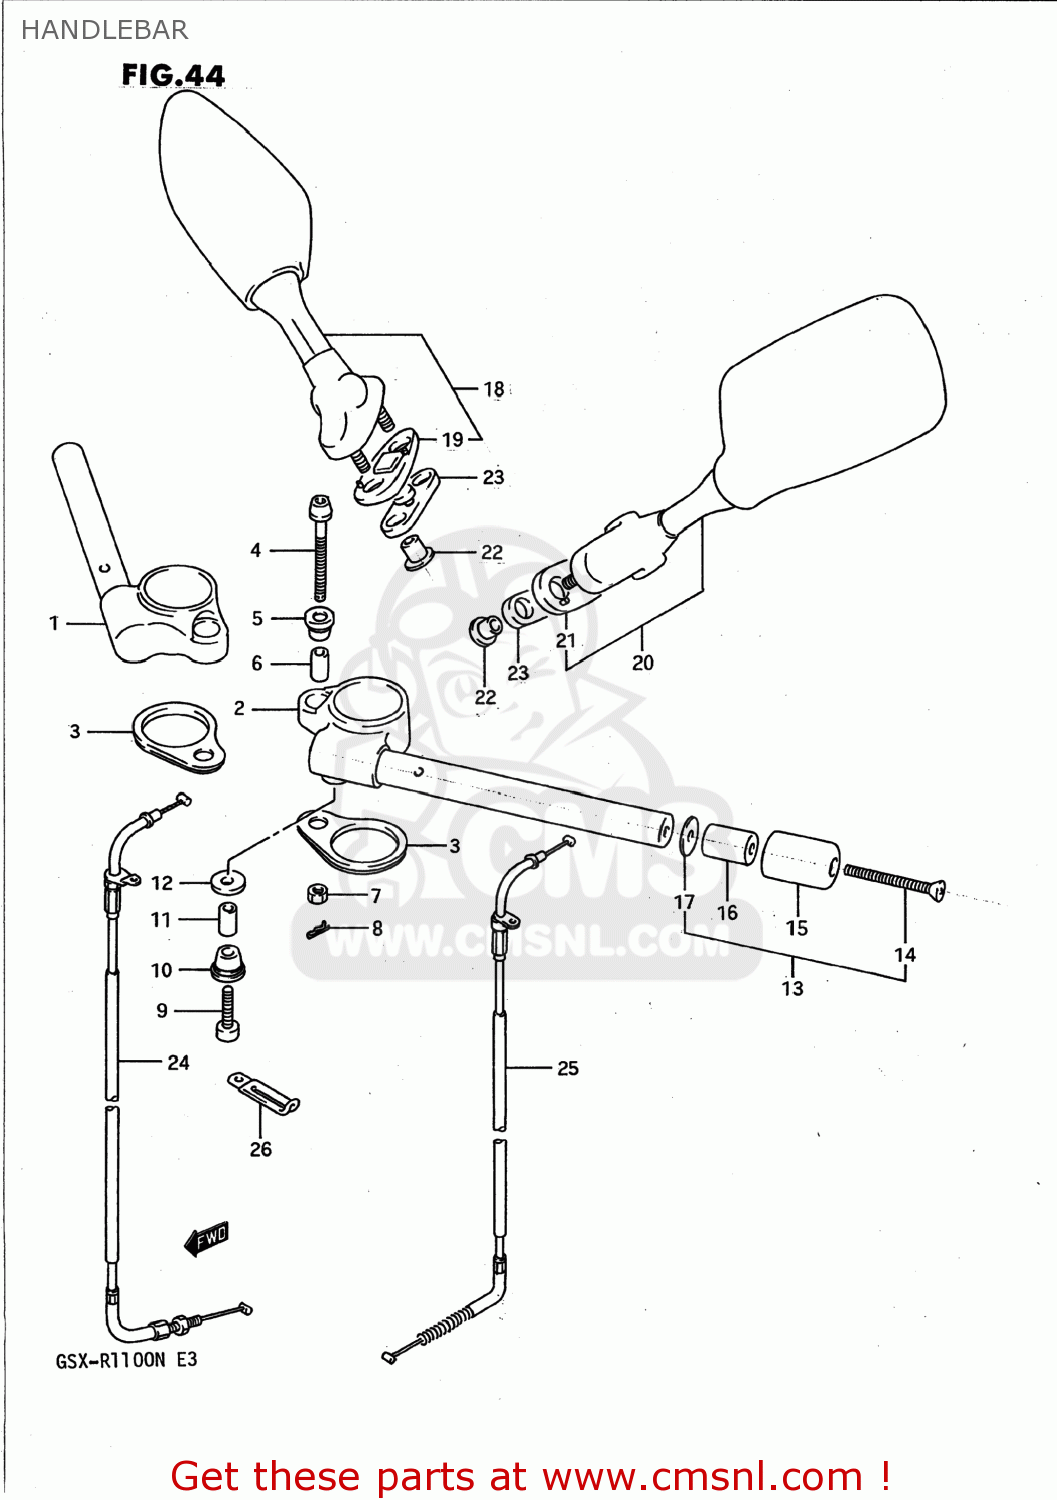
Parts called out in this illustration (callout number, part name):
1	HANDLEBAR,R
2	HANDLEBAR,L
3	CUSHION,HANDLEBAR
4	BOLT,HANDLEBAR
5	CUSHION,HANDLEBAR UPR
6	SPACER,HANDLEBAR
7	NUT 8MM
8	SNAP
9	BOLT, LH
10	CUSHION,HANDLEBAR UPR
11	SPACER,HANDLEBAR
12	CUSHION,HANDLEBAR SPACER
13	BALANCER SET,HANDLEBAR
14	SCREW (L:65)(SUS)
15	CAP,BALANCER
16	BALANCER,HANDLEBAR
17	SPACER,BALANCER
18	MIRROR ASSY,RR VIEW,R
19	GASKET,RR VIEW MIRROR,R (NAS)
20	MIRROR ASSY,RR VIEW,L
21	GASKET,RR VIEW MIRROR,L (NAS)
22	NUT,RR VIEW MIRROR
23	CUSHION,RR VIEW MIRRORR
24	CABLE ASSY,THROTTLE
25	CABLE,STARTER
26	CLAMP
